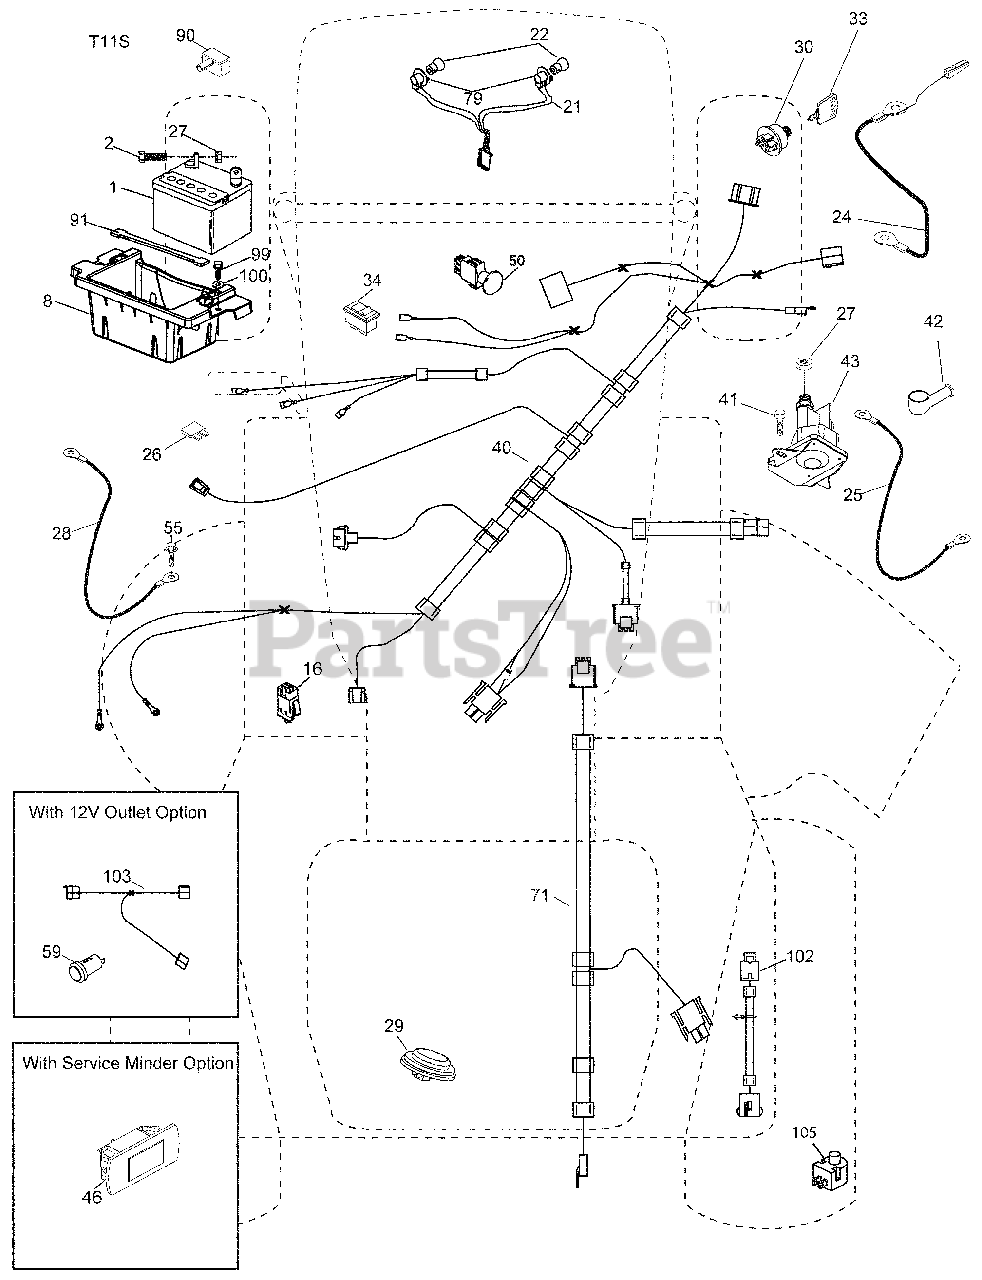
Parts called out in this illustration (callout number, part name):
1	Battery
2	Bolt Hex Head 1/4-20 x 3/4
8	Box Battery
16	Switch Interlock Push-In
21	Harness Socket Light w/4152J
22	Bulb Light
24	Cable Brty
25	Cable Starter
27	Nut Keps Hex 1/4-20 unc
28	Cable, Ground
29	Switch, Seat
30	Switch, Ign
34	Switch Light/Reset
40	Harness Ign. Dash
41	Screw Thd Cut 1/4-20 x 1/2
42	Cover, Terminal
43	Solenoid
46	Gauge Serviceminder Hrmtr
50	Switch PTO
55	Screw Thdrol 5/16-18 x 3/4 TYTT
71	Harness Ign.
79	Socket Asm. Bulb Twistlock
90	Cover Terminal
91	Strap Battery Mount Front
99	Screw Hexwsh Thdrol 1/4-20 x 3/4
100	Washer 9/32 x 7/8 x 16 Ga.
102	Harness Pigtail
105	Switch Reverse TT Pedal Control
